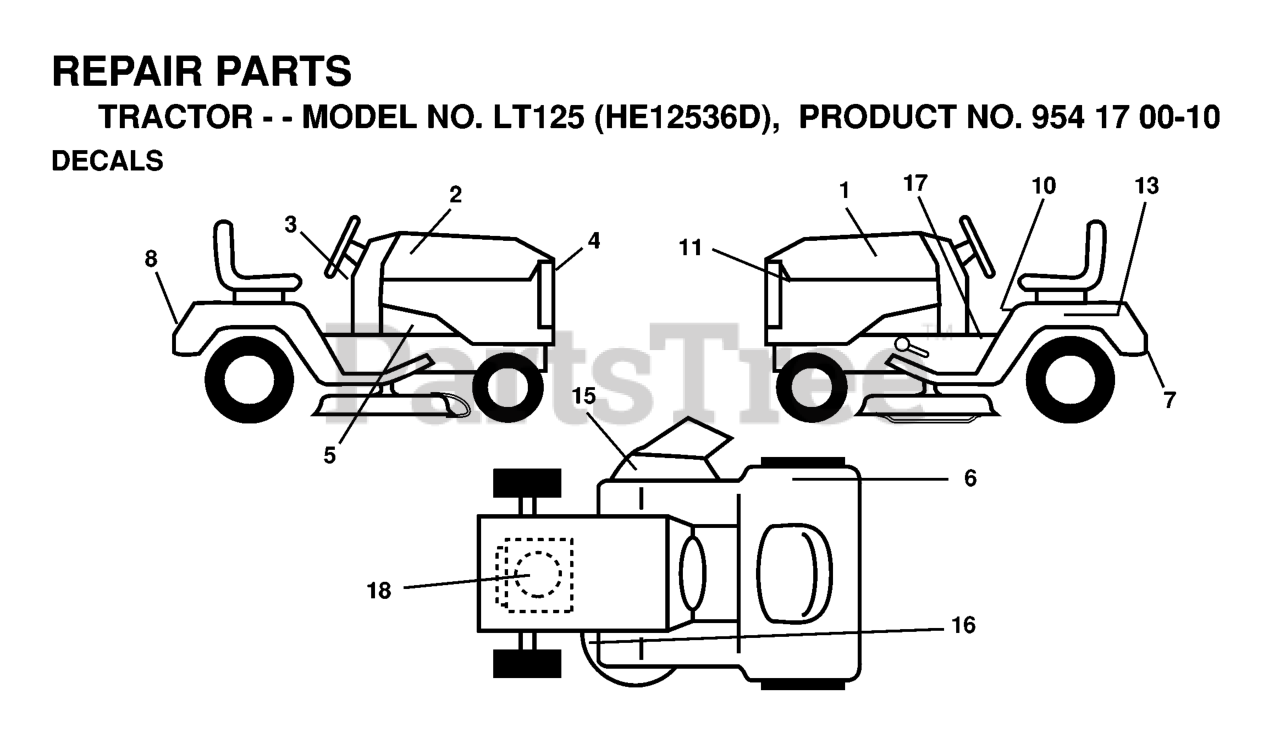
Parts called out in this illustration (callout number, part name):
3	DECAL CERTIFICATION
4	DECAL.GRILLE.HUSQ
5	DECAL
6	DECAL EUROPE STANDARD CE
7	DECAL
8	DECAL FENDER HUSQ
10	DECAL READ OWNER'S MAN SYMS
11	DECAL PNL SIDE
13	DECAL BTRY SYMBOLS
15	DECAL MOWER CUT/FINGER
16	DECAL
17	Decal, Brake/Clutch Symbols
